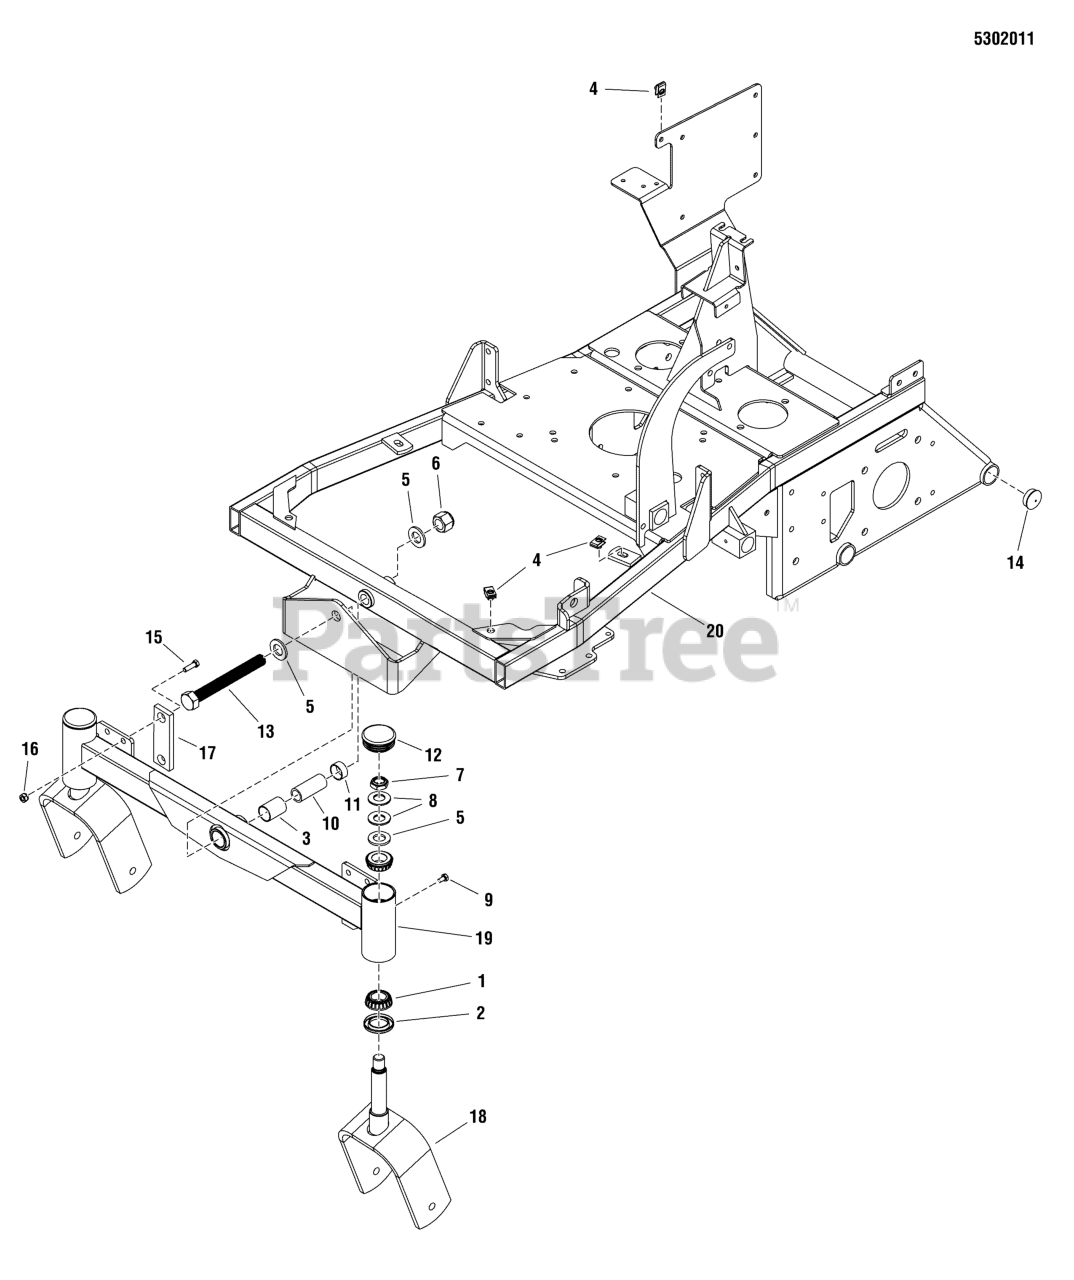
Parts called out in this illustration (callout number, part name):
1	BEARING, TAPERED ROLLER, 1
2	SEAL, GREASE
3	PIVOT BEARING-1.00 X 1.125 ODX1.50
4	BODY CLIP, 5/16-18-7GA MATERIAL
5	WASHER, 3/4 SAE
6	NUT, 3/4-16 HEX NYLON LOCK
7	NUT, 3/4-16, HEX JAM NYLON LOCK
8	WASHER, BELLEVILLE - 1.500 X .755
9	BOLT, 1/4-28 X 1/2, GD5 YZ
10	SPACER, .75 X 1.00 X 2.38
11	PIVOT BEARING, 1.00 X 1.125 OD X .50
12	CAP, GREASE, LOW PROFILE
13	BOLT, 3/4-16 X 6-1/2 YZ GD5
14	PLUG, PANEL, 1.25 - BLACK
15	SCREW, 5/16-18 X 1, PHILLIPS HD, BZ
16	NUT, 5/16-18 HEX NYLON LOCK
17	PAD, FRICTION, .375 X 1.25 X 4.00
18	WELD, CASTER YOKE - RED
19	WELD, FRONT END PIVOT
20	WELD, MAIN FRAME, COMPACT RIDER - RED
